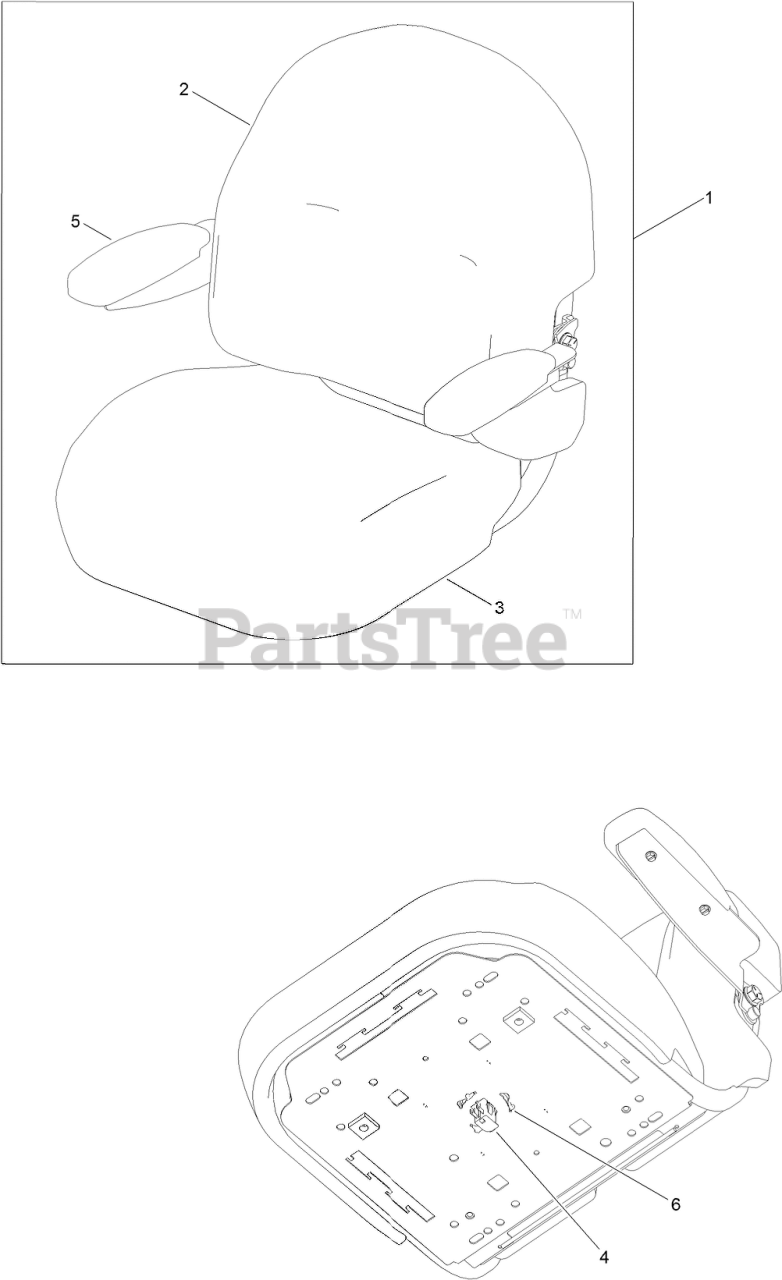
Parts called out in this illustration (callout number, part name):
1	SEAT ASM
2	COVER-SEAT BACK
3	COVER-SEAT BASE
4	SWITCH-BAIL
5	KIT-ARM REST
6	CAP-SWITCH, ACTUATOR
